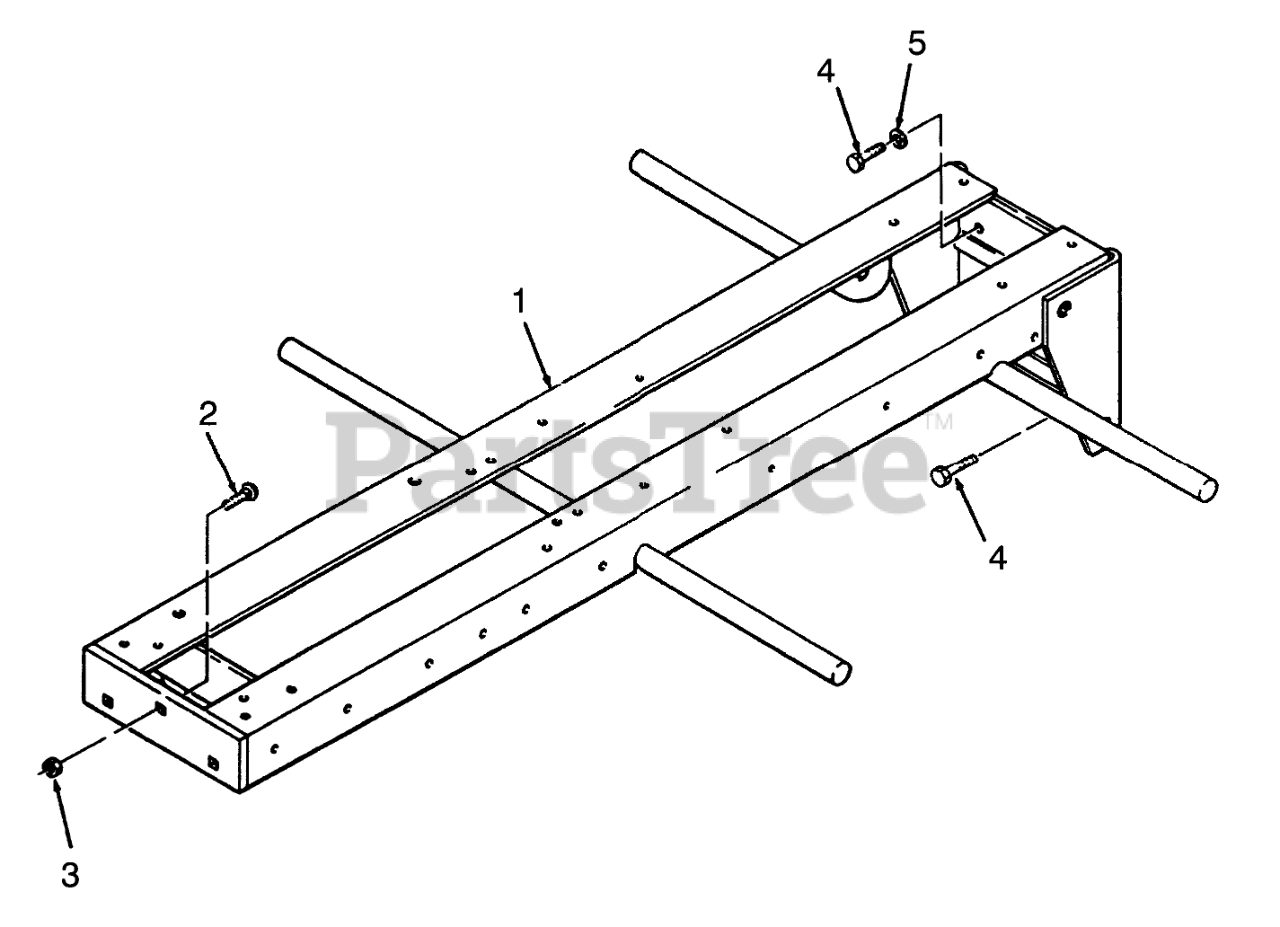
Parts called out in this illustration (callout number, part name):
1	WELD FRAME R
2	BOLT-CARR
3	NUT-LOCK, NI
4	SCREW-HH
5	WASHER-LOCK
